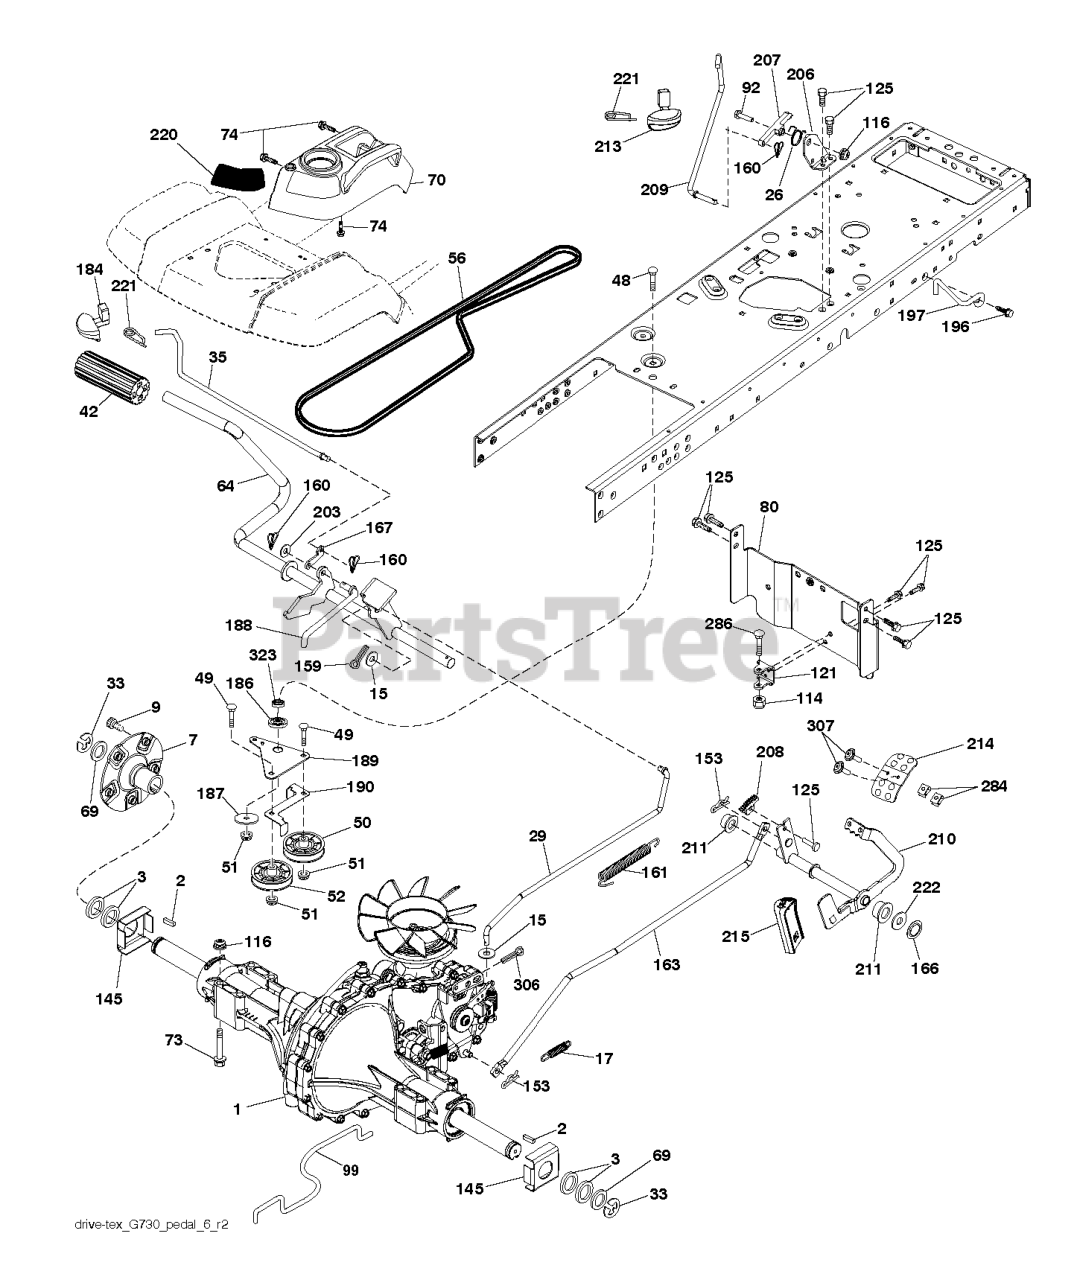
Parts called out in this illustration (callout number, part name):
2	KEY 1/4 X 2.5
7	HUB.ASM.WHEEL.REAR.23"TEX
9	HUB BOLT
15	WASHER
17	SPRING.BRAKE.HG3000/3500
26	SPRING.RETURN.CRUISE
33	E RING HYT
35	ROD .BRAKE. PARKING. GT. HUSQ.
42	PEDAL COVER T
48	BOLT.3/8-16X1.50
50	IDLER.FLAT.910.OFFSET
51	NUT LOCK FLG 3/8-16 UNC
52	IDLER.V-GROOVE.910.OFFSET
56	V-BELT.GROUND.DRIVE.
64	SHAFT.ASM.PEDAL.BRK.CNTR
70	CONSOLE.ASM.RH.GT.FC.HUSQ
73	BOLT HEX FLGHD 5/16-18X3 GR. 5
74	SCREW.HI-LO.CONSOLE
80	STRAP.TORQUE.YT.G700
92	BOLT
99	SPRING.BYPASS.YT.G700
114	NUT.71038.31-18.HEX.NYLOCK
116	NUT LOCK HEX FLANGE 5/16-18
121	BRACKET STRAP TORQUE
125	SCREW
145	WASHER.AXLE.FLANGE.HG-3000
153	RETAINER M
159	COTTER PIN
160	RETAINER CLIP
161	SPRING, RETURN LT
163	ROD PEDAL CONTROL
166	NUT.PUSH.625
167	LATCH.BRAKE.SPRING
184	RB HANDLE.PARKG.BRK.HUS/PRED
186	SPACER.RETAINER
187	WASHER 12/32X2X10GA
188	RP.LINK.CLUTCH.GROUND.DRIVE
189	BELLCRANK.GROUND.DRIVE.TRAPPED
190	KEEPER BELLCRANK ROUND DRIVE
196	SCREW 3/8-16X1
197	BRKT.ANIT-ROTATION.CLUTCH
203	WASHER
206	BRKT.MOUNT.LATCH.CRUIS
207	LATCH.CONTROL.CRUISE
208	GEAR.SECTOR.CONTROL.CR
209	ROD.CONTROL.CRUISE.GT.
210	ROCKER.ASM.PEDAL.CONTR
211	BEARING.NYLON
213	KNOB.CONTROL.CRUSIE.HU
214	PEDAL.FORWARD.HUSQVARNA.DEALER
215	PEDAL.REVERSE.TEX.GT.4
220	REFLECTOR.RH.TEX GT
221	RETAINER.SPRING.CLIP.H
222	WASHER 21/32 X 1-1/4 X 10 GA.
284	NUT.U-CHNL.1/4-20.550DP.350PNL
286	BOLT.5/16-18X2.5
306	PIN COTTER
307	SCREW.MACHINE.CR.1/4-20
323	SLEEVE.BELLCRANK
